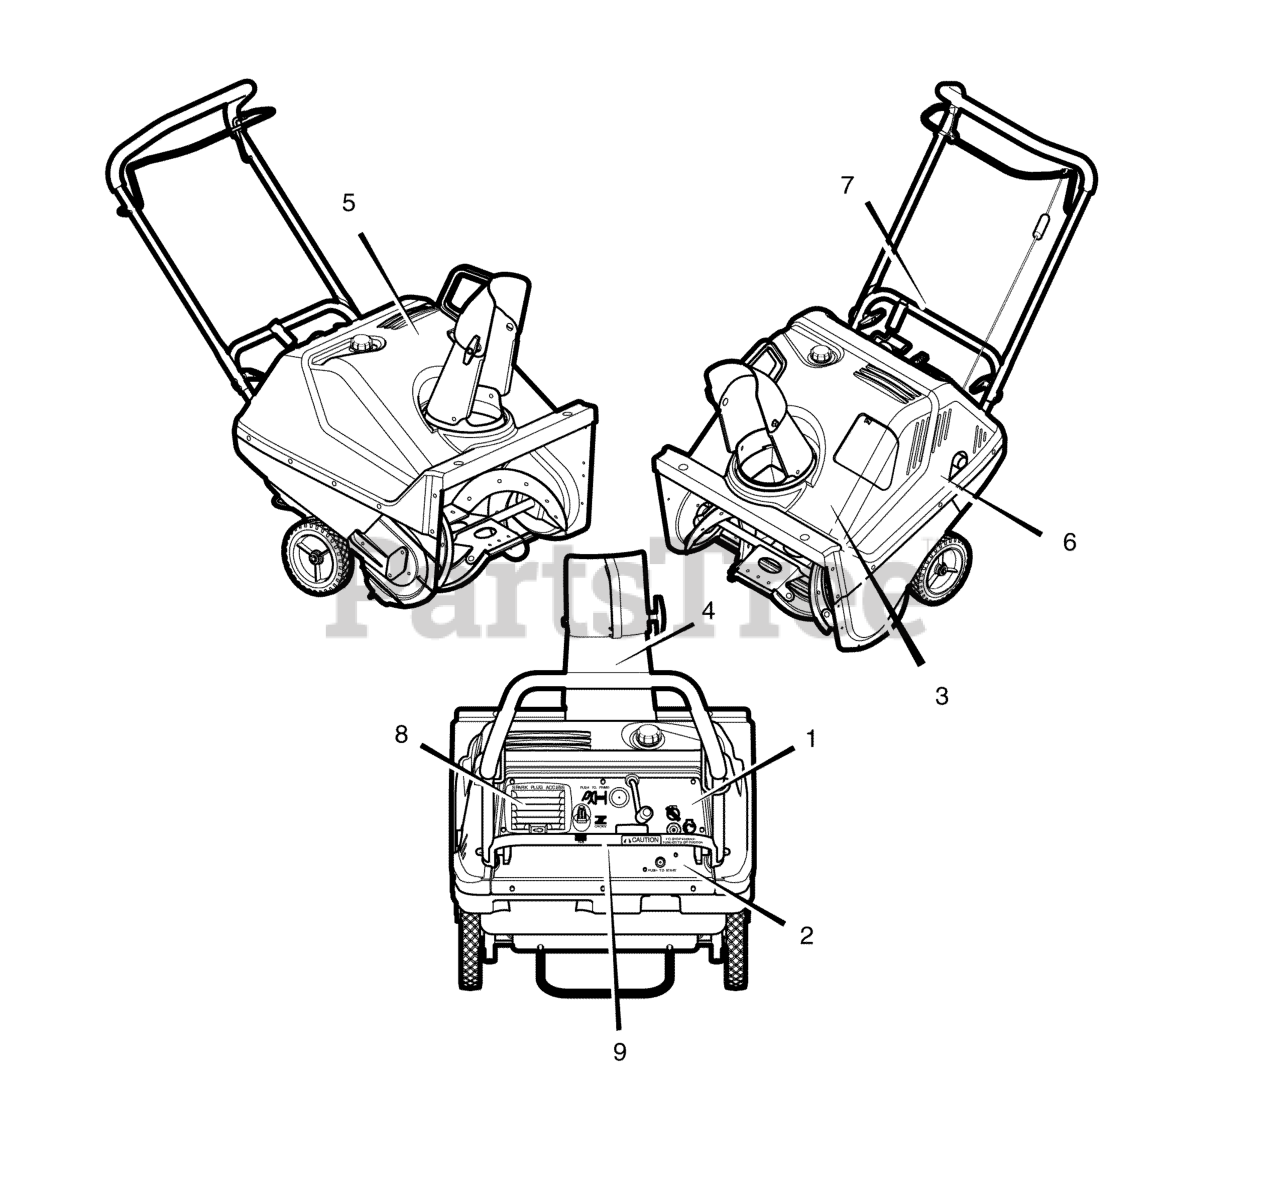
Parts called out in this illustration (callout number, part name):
1	Decal, Panel - 22" ES CANADA
2	Decal, Push To Start
3	Decal, Danger Auger
4	Decal, Danger Chute
5	Decal, 5hp 22" CRAFTSMAN
6	Decal, Danger Muffler
7	Decal, Auger Control
8	Decal, Spark Plug Access
9	Decal, Electric Plug Orientation
